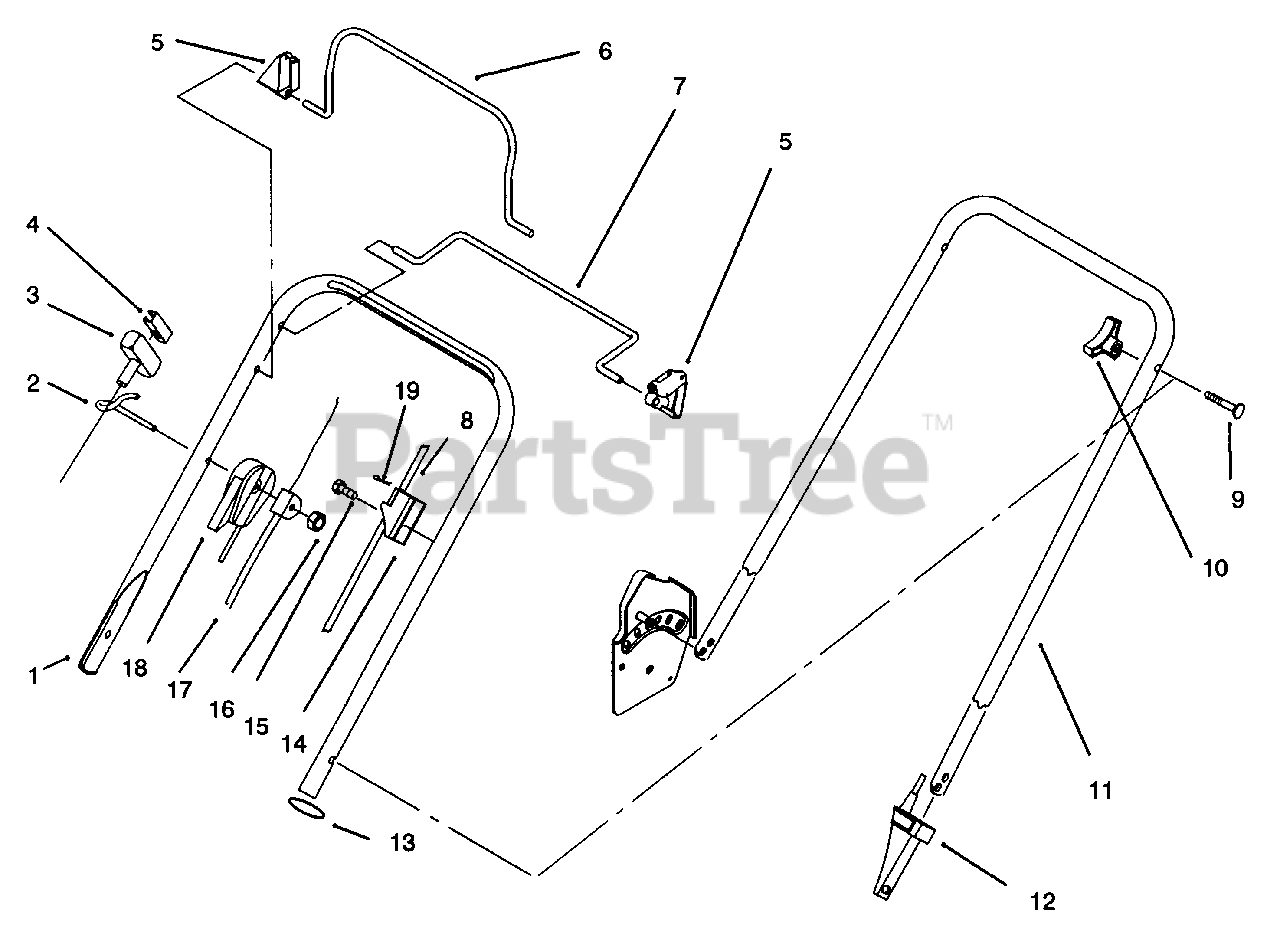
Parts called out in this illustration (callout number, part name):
1	Handle-Upper
2	Guide-Rope
3	Handle-Starter
4	Clip-Rope Insert
5	Stop-Pivot
6	Bail-Brake
7	Bail-Control Self Propelled
8	Cable-Traction
9	Screw-Handle
10	Knob-Handle
11	Handle-Lower
12	Anchor-Cable, (Lower) Self Propelled
13	Tie Strap
14	Anchor-Cable (Upper) Self Propelled
15	Screw
17	Cable-Brake
18	Cable-Throttle
19	Clip-Hairpin
